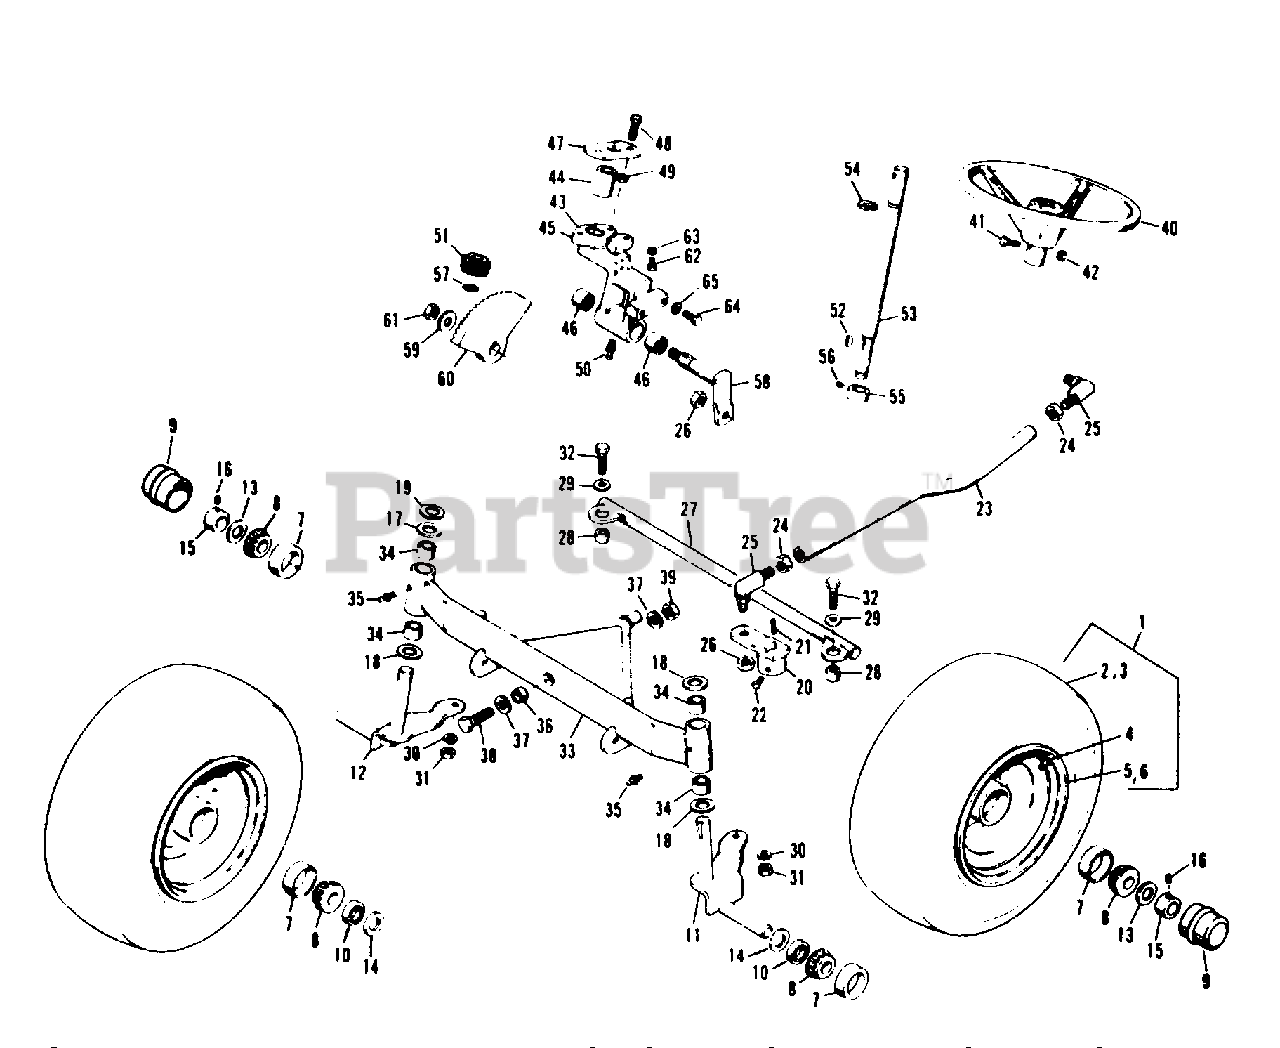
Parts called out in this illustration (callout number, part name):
1	Wheel & Tire Assy.
4	Valve Stem & Cap
5	Wheel-Sub Assy.
6	Wheel (Front)
7	Bearing, Cup
8	Bearing, Cone (Without Seal)
9	Hub Cap
11	Spindle Assy. L.H.
12	Spindle Assy. R.H.
15	Collar, Set
16	Cup Pt. Socket Head Set Screw 5/16"-18 N.C. x 5/16"
17	Washer (Use Beneath Snap Ring)
19	Ring, Retaining
20	Arm Assy., Strg. L.H.
22	Cup Pt. Socket Head Set Screw, 5/16"-18 N.C. x 1/2"
24	Hex Nut, Jam, 1/2"-20 N.F.
25	Joint, Ball
26	Hex Nut Jam Lock, 1/2" 20 N.F.
27	Link Assy., Drag
29	Washer, Plain 3/8"
30	Lock Washer, 3/8"
31	Hex Nut, Full, 3/8"-16 N.C.
32	Hex Cap Screw, 3/8"-16 N.C. x 1-1/4"
33	Axle Assy., Front
35	Fitting, Grease
37	Plain Washer, 1/2"
38	Hex Cap Screw, 1/2"-13 N.C. x 1-3/4", Grade 5
39	Hex Nut, Full Lock, 1/2"-13 N.C.
40	Steering Wheel
41	Hex Head Screw, 5/16"-18 N.C. x 1-1/4"
42	Hex Nut, Lock 5/16"-18 N.C.
43	Steering Bracket, Casting
44	Bushing, Steering
45	Casting and Bearing
46	Bearing, Needle
47	Plate, Steering
48	Hex Cap Screw, 3/8"-16 x 1-1/4"
49	Hex Jam Nut, 3/8"-16
50	Fitting, Grease
51	Pinion, 15T, Bevel
52	Key, Woodruff, No. 6 5/32" W. x 5/8" Dia.
53	Shaft, Steering
54	Ring, Retaining
55	Collar, Set
56	Set Screw, 5/16"-18 N.C. x 1/4"
57	Ring, Retaining
58	Arm Assy. Steering
59	Plain Washer, 7/16"
60	Gear, 23T, Bevel
61	Hex Nut, Lock, 7/16"-14 N.C.
62	Hex Cap Screw, 3/8"-16 N.C. x 3/4"
63	Lock Washer, 3/8"
64	Hex Cap Screw, 3/8"-16 N.C. x 7/8"
65	Lock Washer, 3/8"
